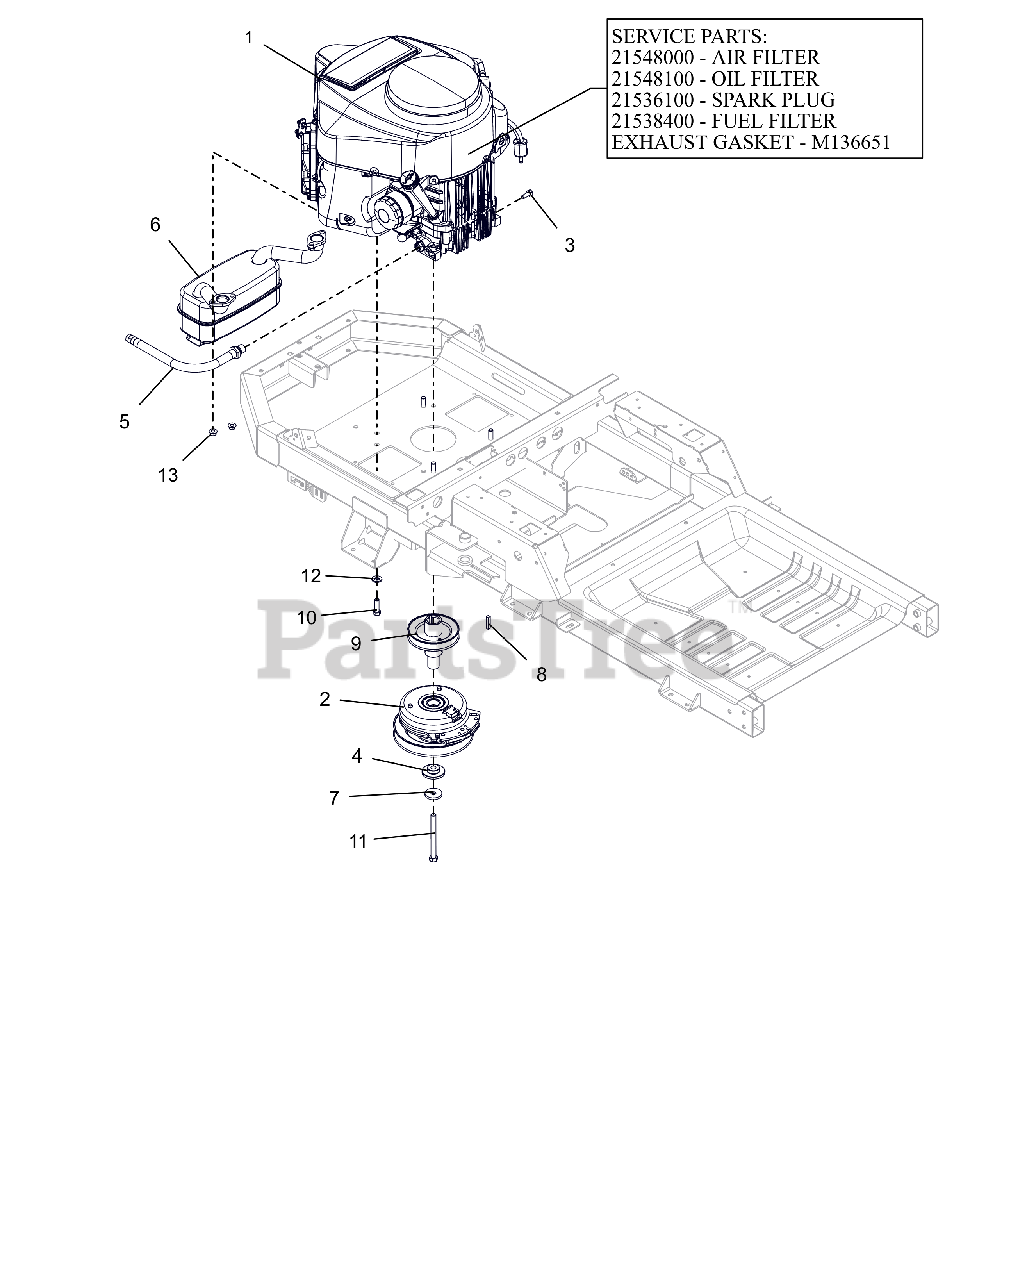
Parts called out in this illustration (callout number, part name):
1	ENGINE, KAWASAKI FR651V 22HP
1	AIR FILTER, KAWASAKI FR
1	OIL FILTER, KAWASAKI FR
1	PLUG, SPARK
1	FUEL FILTER - KAWASAKI
1	GASKET, MUFFLER #
2	CLUTCH,105FTLB MONOPOLE 6.83"
3	BLT, HEX M8-1.25X20 G8.8 ZCC
4	BSHG-FLG .469X1.06X.574X2.0
5	HOSE, OIL DRAIN
6	MUFFLER - KAWASAKI
7	WASHER, 7/16" SPRING DISK
8	KEY-SQ .25 X 1.25 X .25 SAE
9	WLDMT, DRIVE SHEAVE-X
10	BLT, HEX .38-16X1.25 G5 ZCC NT
11	BLT, HEX .44-20X4.50 G8 ZCC NT
12	WASHER, 3/8" SPRING DISC
13	NUT-LK-TOP-FLG M8 ZCC
